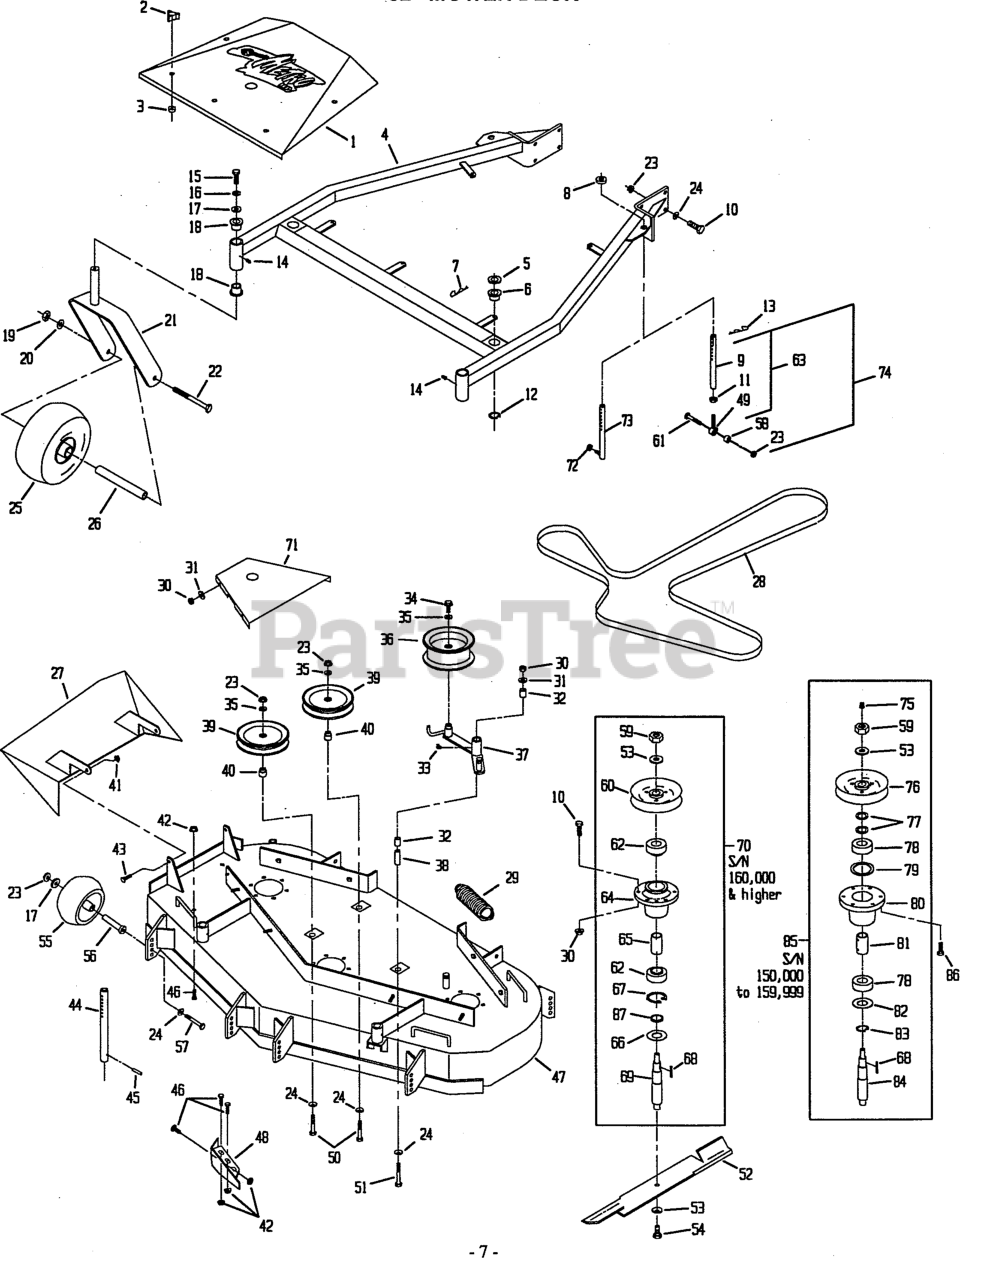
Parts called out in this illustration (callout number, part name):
1	Shield, Belt W/Decals
2	Knob, Belt Shield
3	Washer, Belt Cover
4	Support Weldmt W/Bushings &Decals
5	Spacer, Front Deck Support
6	Bushing, Deck Support
7	Hairpin, Cotter
8	Spacer, Blade Drive
9	Link, Deck Support
10	Screw, Hex Cap 3/8-16x1-1/4
11	Nut, Reg Hex 3/8-24
12	Ring, Retaining
13	Hairpin, Cotter
14	Zerk, Straight 1/8
15	Screw, Hex Cap 3/8-16x1
16	Washer, 3/8 Heavy Spring
17	Washer, Swivel
18	Bearing, Flange
19	Nut, Reg Hex 1/2-13
20	Washer, Lock Hlcl Spg 1/2 Reg
21	Caster Weldmt
22	Screw, Hex Cap 1/2-13x6
23	Nut, Whizlock 3/8-16
24	Washer, Disc Spring 3/8
25	Tire & Wheel Assembly
26	Spacer
27	Chute Weldmt, Discharge
28	Belt, Deck Drive
29	Spring, Extension
30	Nut, Nyloc 3/8-16
31	Washer, Flat Std 3/8
32	Pivot, Bearing
33	Zerk, 90 Degree 1/4-28
34	Bolt, Whizlock 3/8-16x1
35	Washer, Flat 3/8 SAE
36	Pulley, Idler
37	Arm, Weldmt
38	Bushing, Idler Pivot
39	Pulley, Idler
40	Bushing, Idler
41	Nut, Nylock 5/16-18
42	Nut, Whizlock 5/16-18
43	Screw, Hex Cap 5/16-18x1
44	Rod, Deck Support
45	Rollpin, 1/4x1-1/2
46	Screw, Hex Cap 5/16-18x5/8
47	Deck Weldmt W/Decals, Discharge Baffle & Support Rods
48	Baffle, Discharge
49	Ball Joint
50	Screw, Hex Cap 3/8-16x2-3/4
51	Screw, Hex Cap 3/8-16x3-1/2 G8
52	Blade, 16.25
53	Washer, Spring Disc
54	Screw, Hex Cap 5/8-11x1
55	Roller, Antiscalp
56	Bushing, Roller
57	Screw, Hex Cap 3/8-16x4 G8
58	Bushing, Spacer
59	Nut, Reg Hex 5/8-18
60	Sheave, W/Hub
61	Screw, Hex Cap 3/8-16x1-3/4
62	Bearing
63	Link, Assembly
64	Housing, Spindle
65	Spacer, Bearing
66	Guard, Bearing-Bottom
67	Ring, Snap
68	Key, Machine
69	Shaft, Spindle
70	Housing, Cutter Assembly
71	Shield, Belt
72	Nut, Torque 3/8-24
74	Kit, Link Assembly
75	Zerk, Straight 1/4-28
76	Sheave, W/Hub
77	Washer, .060
78	Bearing, Spindle
79	O-Ring, Cutter Housing
80	Housing, Bearing
81	Spacer, Bearing
82	Seal, Dust
83	Ring, Snap
84	Shaft, Spindle
86	Screw, Hex Taptite 3/8x16x1
87	Spacer
